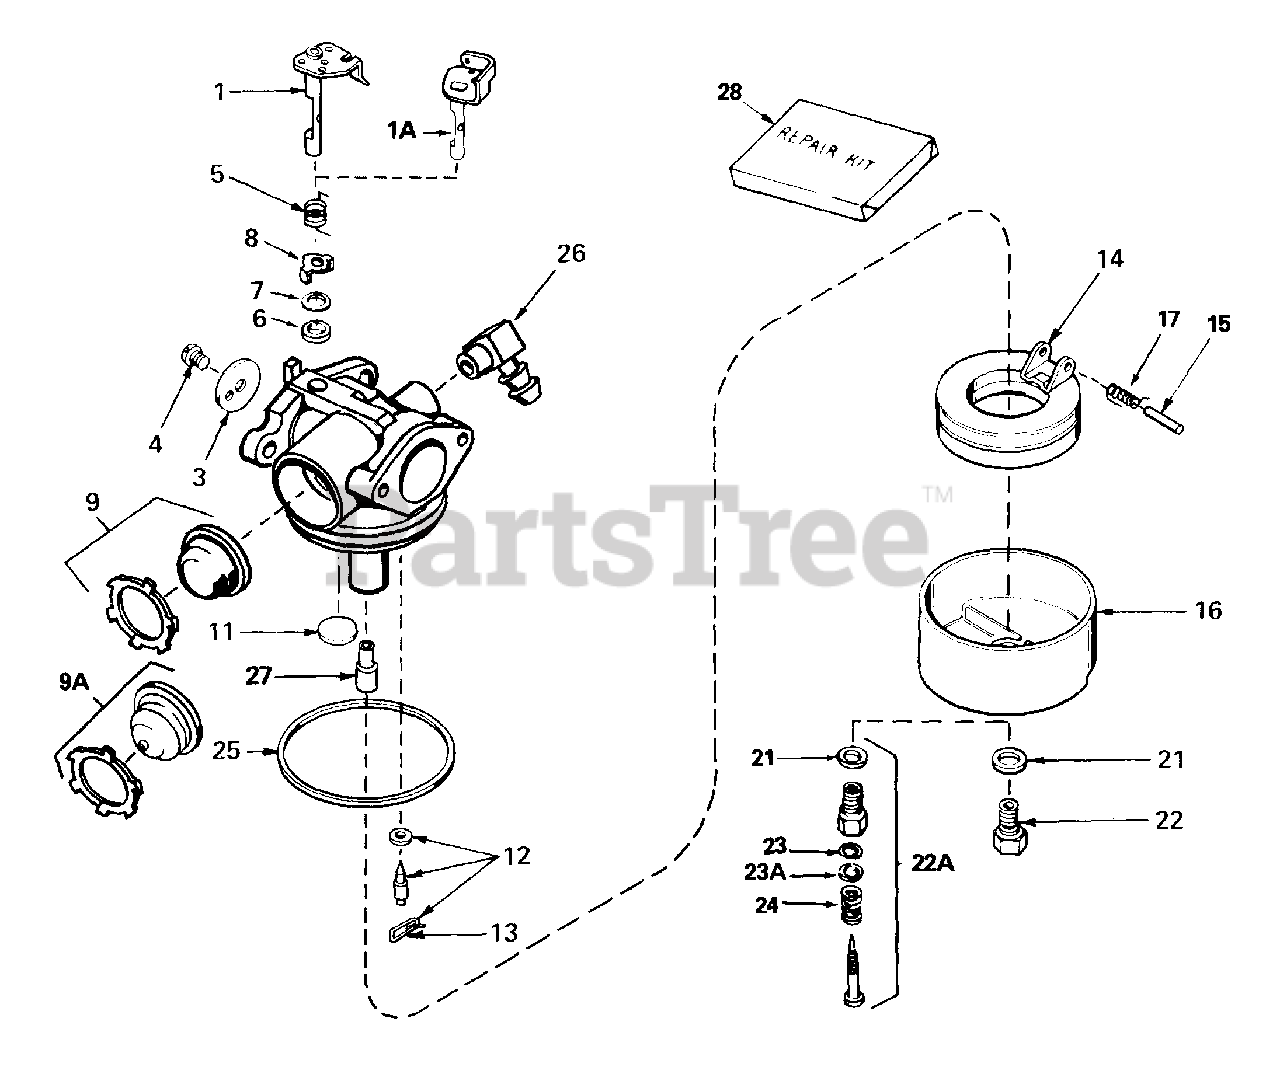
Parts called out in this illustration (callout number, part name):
1	"Shaft & Lever Assy., Throttle
3	Shutter, Throttle
4	Screw, Throttle shutter
5	Spring, Return
6	Seal, Dust
7	Washer, Flat
8	Retainer, Dust seal
9	Bulb & Retainer, Primer
11	Plug, Welch
12	Inlet Needle, Seat & Clip Assy.
13	Clip, Inlet needle
14	Float, Carburetor
15	Shaft, Float
16	Bowl, Float
21	Gasket, Bowl-to-body
22	Nut, Float bowl (Extended)
25	Gasket, Bowl-to-body
26	Fitting, Fuel inlet
